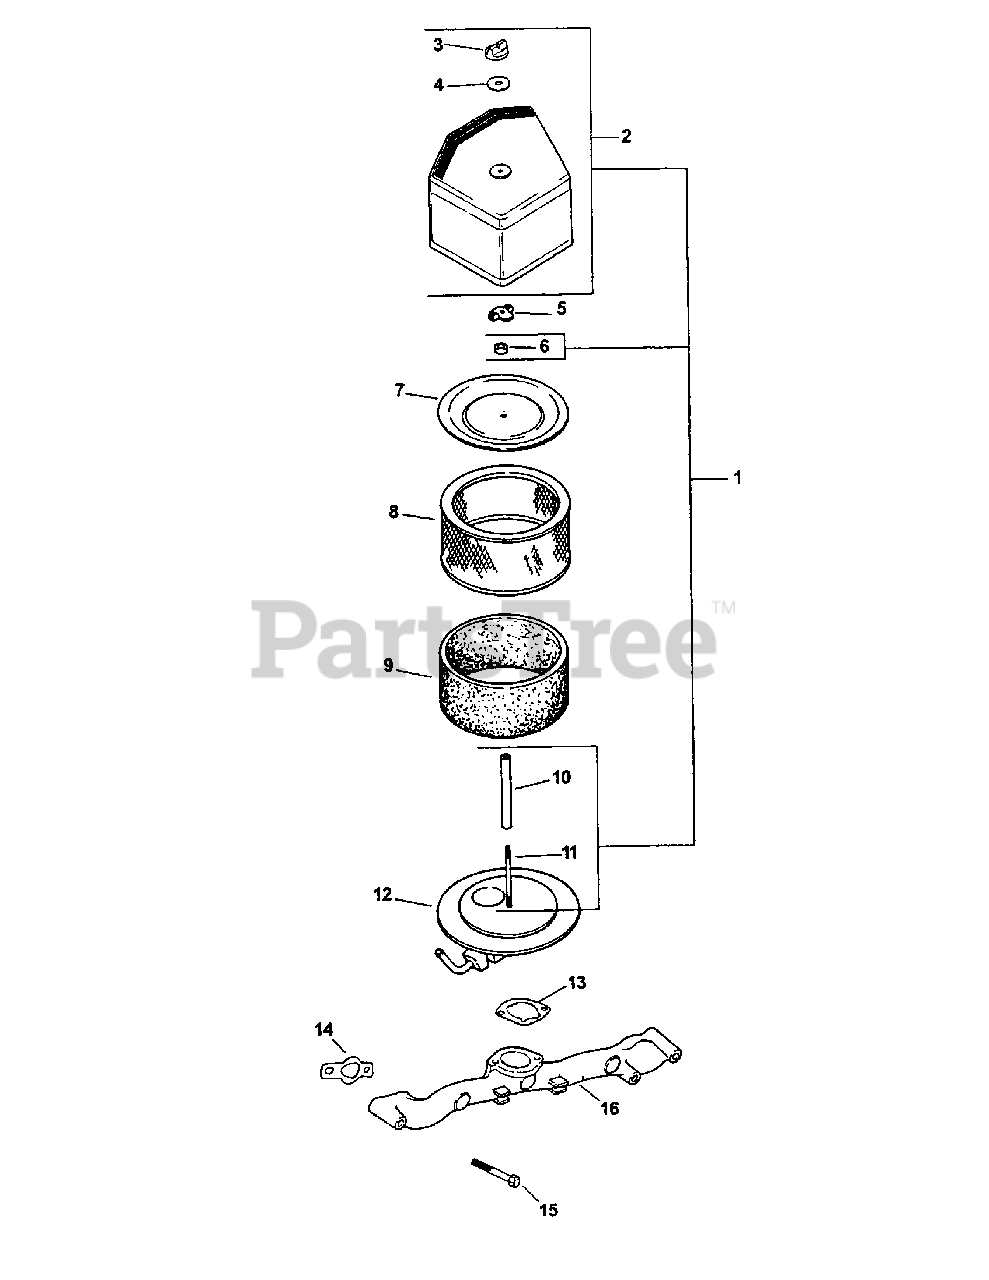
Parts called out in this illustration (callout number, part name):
1	Kit, Air Cleaner
2	Kit, Air Cleaner Cover
3	Knob, Cover
4	Gasket, Air Cleaner Cover Knob
5	Wing Nut
6	Nut, Hex Flange
7	Cover, Air Cleaner Element
8	Element, Air Cleaner
9	Precleaner, Element
12	Elbow, Air Cleaner
13	Gasket, Air Cleaner Base
14	Gasket, Intake Manifold
15	Screw, Hex Flange
16	Manifold, Intake
